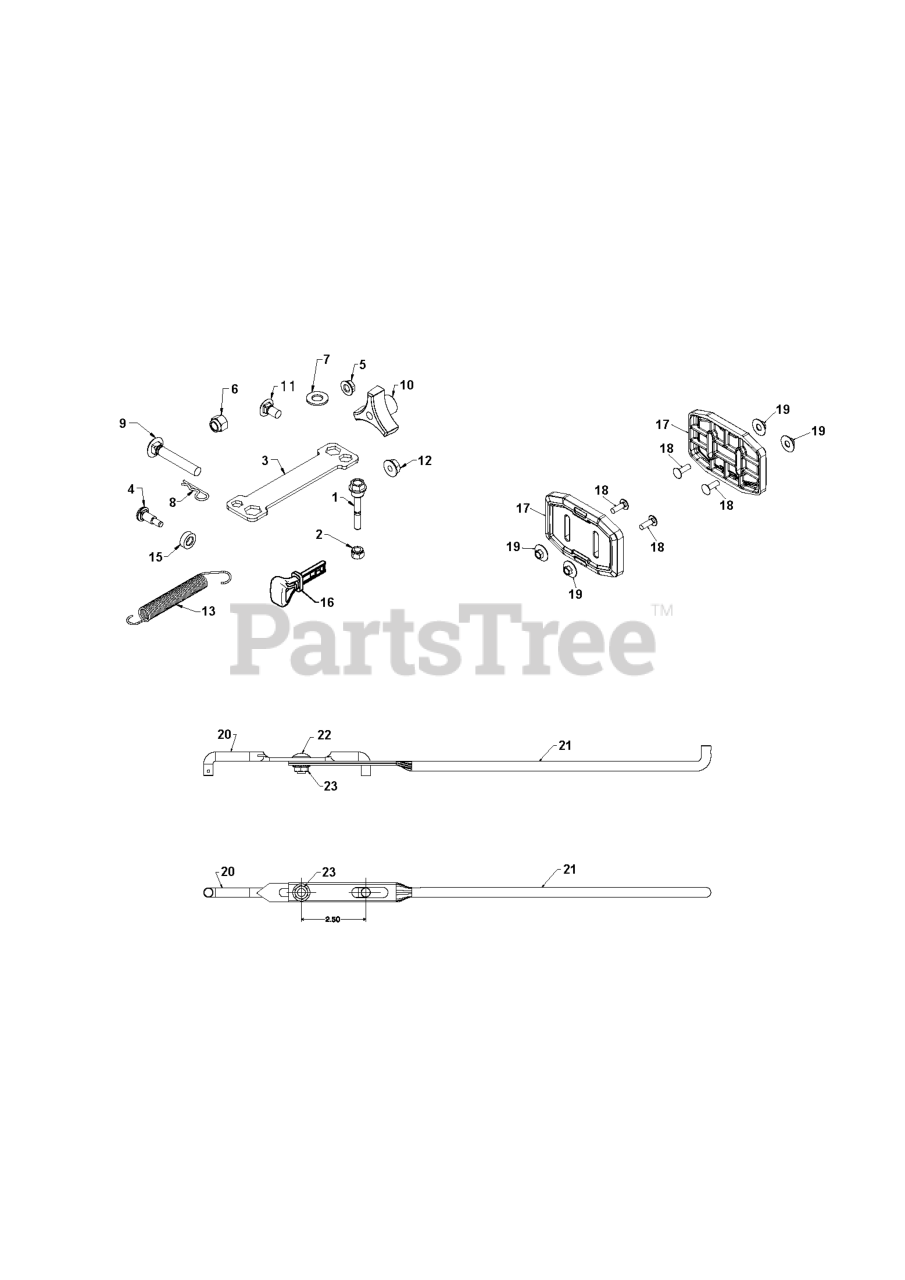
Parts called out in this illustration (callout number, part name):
1	BOLT.1/4-20 X 1-13/16 SHEAR
2	LOCKNUT.NYLOC.1/4-20
3	WRENCH.SNOWTHROWER.ZINC.YZ
4	BOLT.CARR.W.3125 SHLDR..25-20
4	BOLT, SHOULDER
5	NUT.HEX.FLANGE.1/4
6	NUT
7	WASHER
8	SPRING RETAINER
9	BOLT 3/8-16 X 2-1/4
10	KNOB.HANDLE.3/8.TRI-POINT.BLAC
11	BOLT CAR BLK 5/16-18 X 5/8
12	NUT.LOCK.5/16-18
12	LOCKNUT-FLANGE 5/16-18
13	SPRING.DEFLECTOR.REM.CHUTE
15	WASHER.NYLON.326 X.625 X.205
16	KEY SET(2 KEYS) SKSN0407.1
17	PLATE.SKID.SHOE.COMPOSITE
18	BOLT.CARR.5/16-18X1.BLACK
19	NUT.HEX.FL 5/16-18 TOP LCK BLK
20	ROD.SHIFTER.TOP.HYD
21	ROD, LOWER, SPEED CONTROL
22	BOLT
23	NUT.FLANGE.5/16
